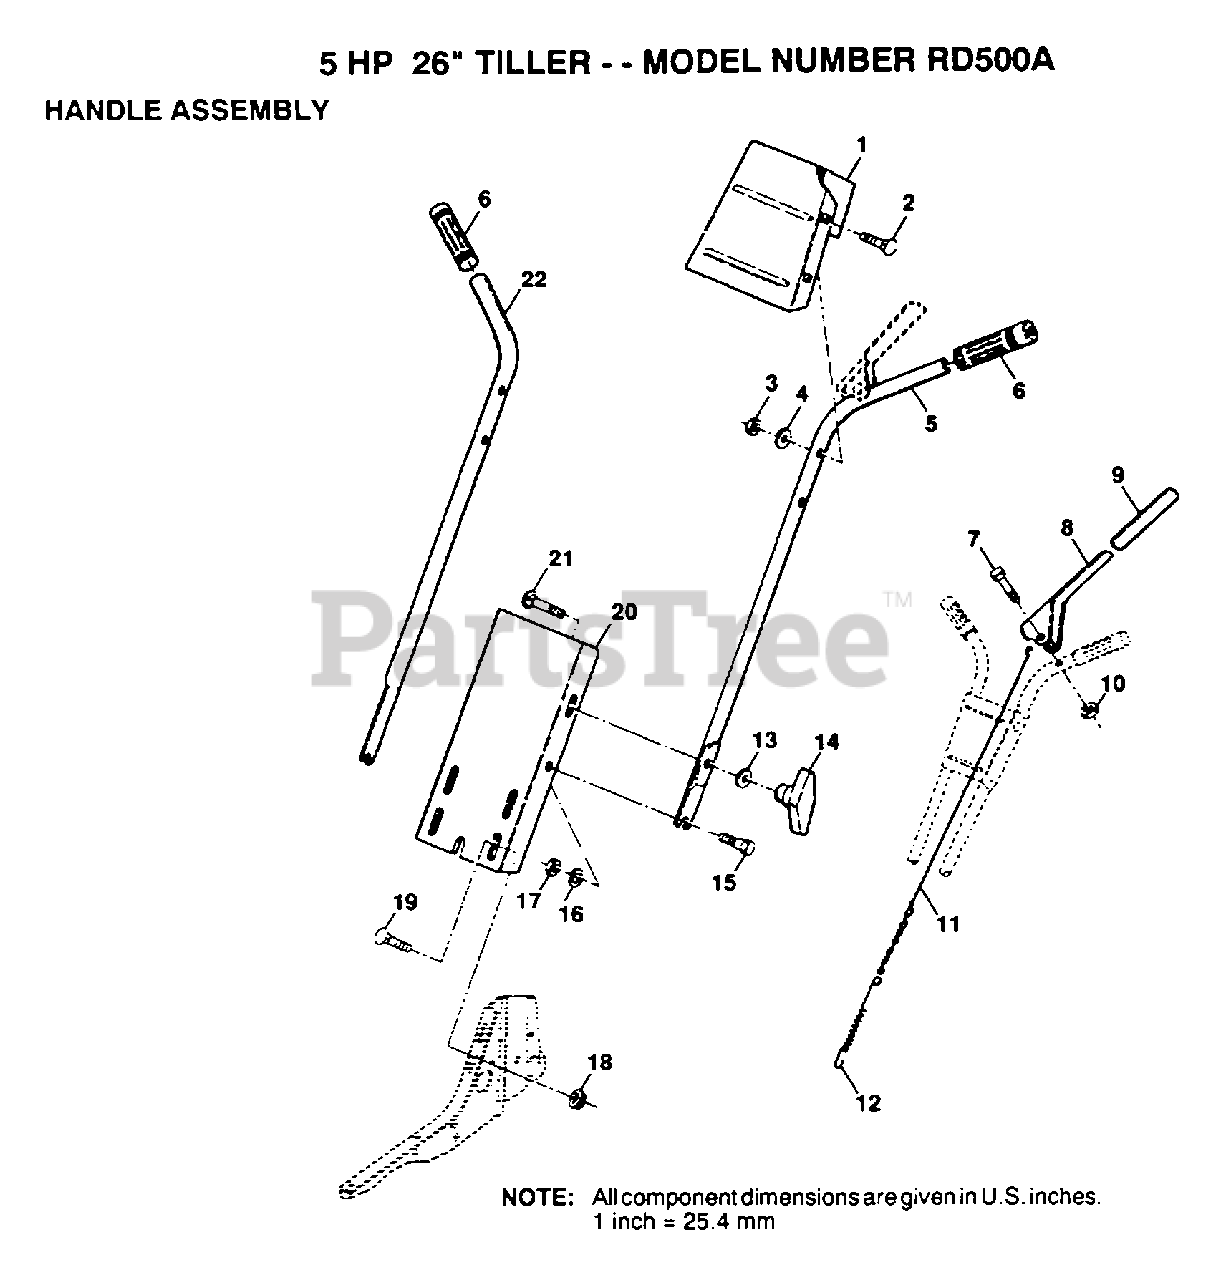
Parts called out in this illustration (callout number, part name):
1	HANDLE BRACKET
2	BOLT
4	WASHER
7	BOLT.HEX.5/16-1.5
9	GRIP T
12	SPRING EXT TI
13	WASHER
16	LOCKWASHER
17	NUT.HEX.5/16-18
18	NUT
19	BOLT
20	"PANEL,HANDLE"
21	BOLT
